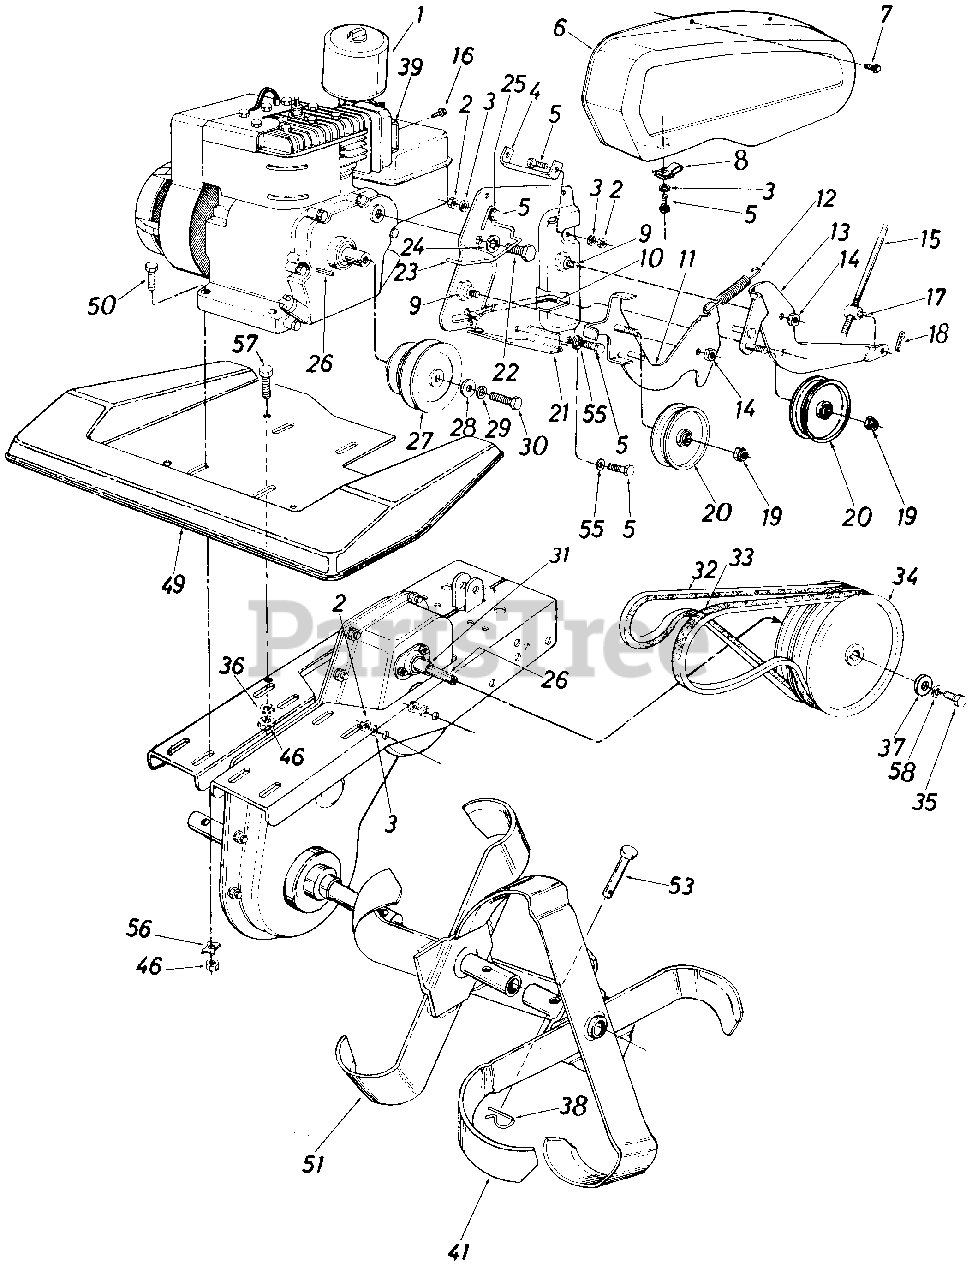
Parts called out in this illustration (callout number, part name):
1	Engine
2	Hex Nut 1/4-20 Thd.
3	L-Wash. 1/4" I.D.
4	Support Bracket
5	Hex Bolt 1/4-20 x .75" Lg.
8	"U"-Type Speed Nut
9	Shoulder Bolt .625" Dia. x .170" Lg.
10	Control Rod
11	Reverse Idler Brkt. Ass'y.
12	Spring-Idler Brkt.
13	Forward Idler Brkt. Ass'y.
14	Hex Cent. L-Nut 3/8-16 Thd.
15	Clutch Control Rod
16	Hex Self-Tap Scr. #8-32 x.38" Lg.
17	Ferrule
18	Inter. Cotter Pin
19	Hex Jam Nut 3/8-24 Thd.
20	Fl-Idler w/Flanges 3.12 O.D. x .75
21	Clutch Mounting Plate
22	Hex Bolt 5/16-24 x .62" Lg.
23	Belt Guard Rod
24	L-Wash. 5/16" I.D.
25	Fl-Wash. 1/4" I.D.
26	Sq. Key 3/16" x 1.50" Lg.
27	Engine Pulley
28	Fl-Wash. 3/8" I.D. x 1.00"
29	L-Wash 3/8" I.D.
30	Hex Bolt 3/8-24 x 1.25" Lg.*
31	Spacer .635 I.D. x .88 O.D. x 1.035 Lg.
32	"V"-Belt 1/2" x 41" Lg. Reverse
33	"V"-Belt 1/2" x 37" Lg. Forward
34	Chain Case Pulley 6.0" Dia.
35	Hex Bolt 5/16-18 x 1.0" Lg.
36	Shake-Proof Wash.
37	Fl-Wash. 5/16" I.D. x 1.120
38	Internal Cotter Pin 1/2" Dia.
39	Deflector
41	See Tine Chart Below
51	See Tine Chart Below
55	Bell-Wash.
56	Shake-Proof Wash.
57	Hex Bolt 5/16-18 x .75" Lg.
58	L-Wash. 5/16" I.D.
